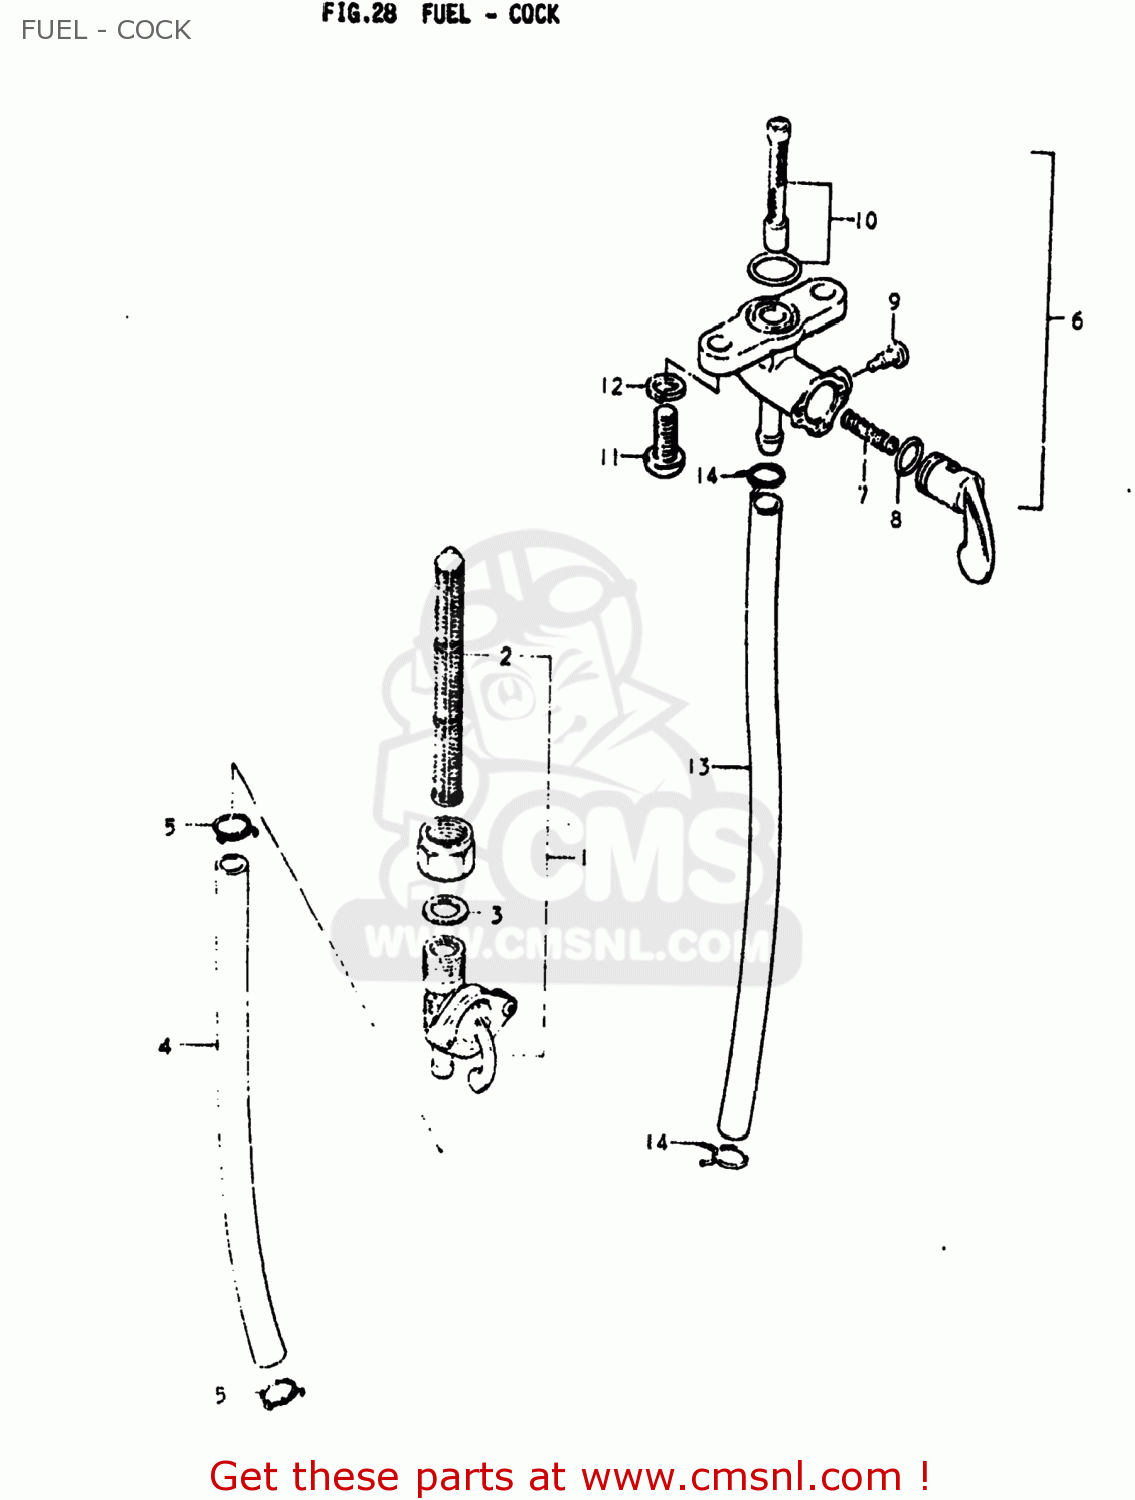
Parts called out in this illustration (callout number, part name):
1	COCK ASSY,FUEL
2	FILTER,FUEL
3	GASKET,FUEL COCK (NAS)
4	HOSE
5	CLIP
6	COCK ASSEMBLY,FUEL
7	SPRING,FUEL COCK VALUE
8	O RING,LEVER
9	SCREW
10	FILTER SET FUEL
11	SCREW
12	LOCK WASHER
13	HOSE
14	CLIP
